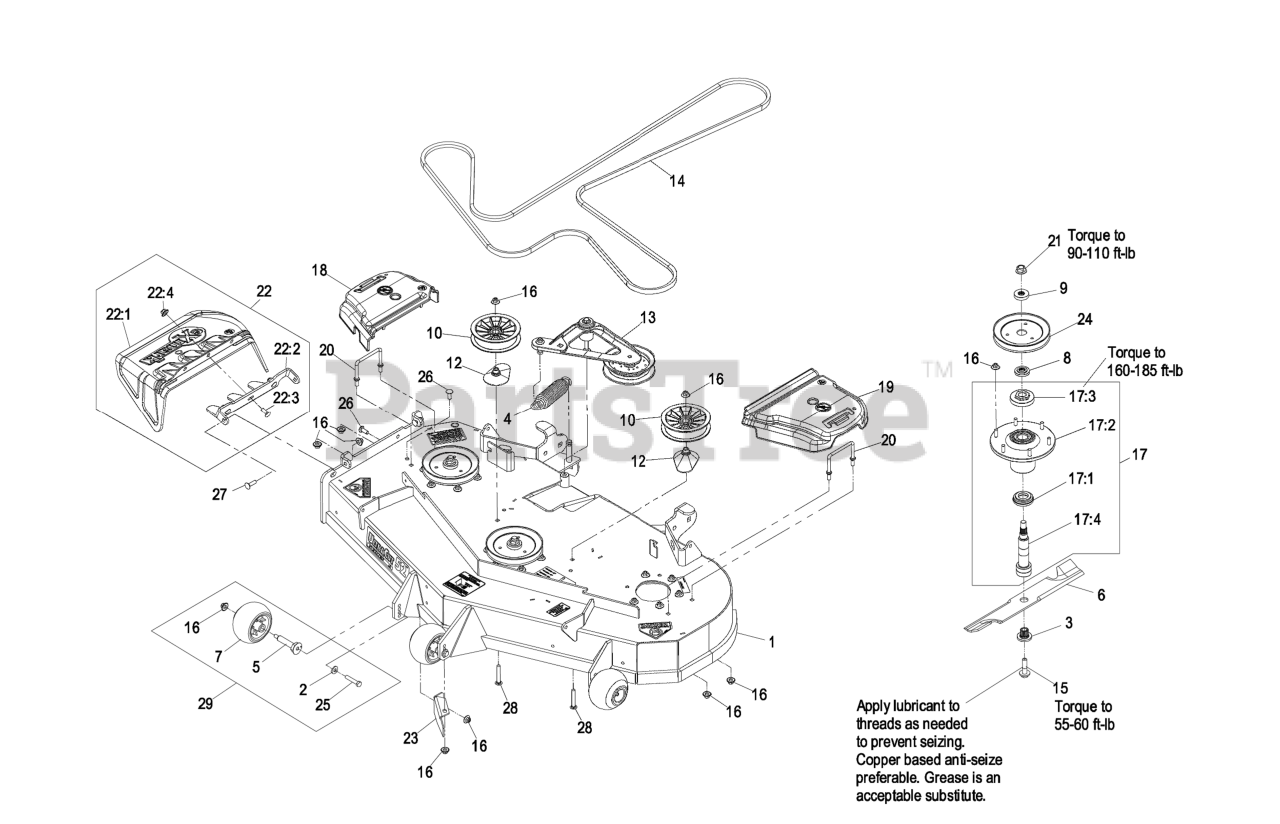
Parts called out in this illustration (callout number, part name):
1	ASM,DECK W/ DECALS 52
2	WASHER-BELLEVILLE
3	BUSHING,SPLINED
7	ROLLER-SCALP, ANTI
8	SPACER,SPLINED STEPPED
9	SPACER,SPLINED
10	PULLEY,IDLER 5"
12	SPACER-PULLEY
14	BELT,V-B X 186.00"
15	SCREW,SEMS 1/2-20 X 2.19
16	Nut-Nyloc 3/8-16 Flg
17	ASM,SPINDLE HOUSING
17:1	GUARD,BOTTOM
17:2	ASM,CUTTER HOUSING
17:3	NUT, SPINDLE 7/8-14
17:4	SPINDLE,DOUBLE SPLINE
18	COVER-BELT, RH
19	COVER-BELT, LH
20	WIREFORM-COVER
21	NUT-FLANGE, CENTERLOCK
22	ASM,DISCHARGE CHUTE
22:1	CHUTE,DISCHARGE
22:2	BRACKET,DISCHARGE CHUTE
22:3	SCREW-CARR
22:4	Nut-Nyloc 3/8-16 Flg
23	BAFFLE,DISCHARGE 52/60
24	SHEAVE,BLADE DRIVE
25	SCREW-HH
26	SCREW-CARR
27	Bolt-Carriage 3/8-16 X 1 1/4
28	SCREW-CARR
30	Asm, Deck Complete 526
